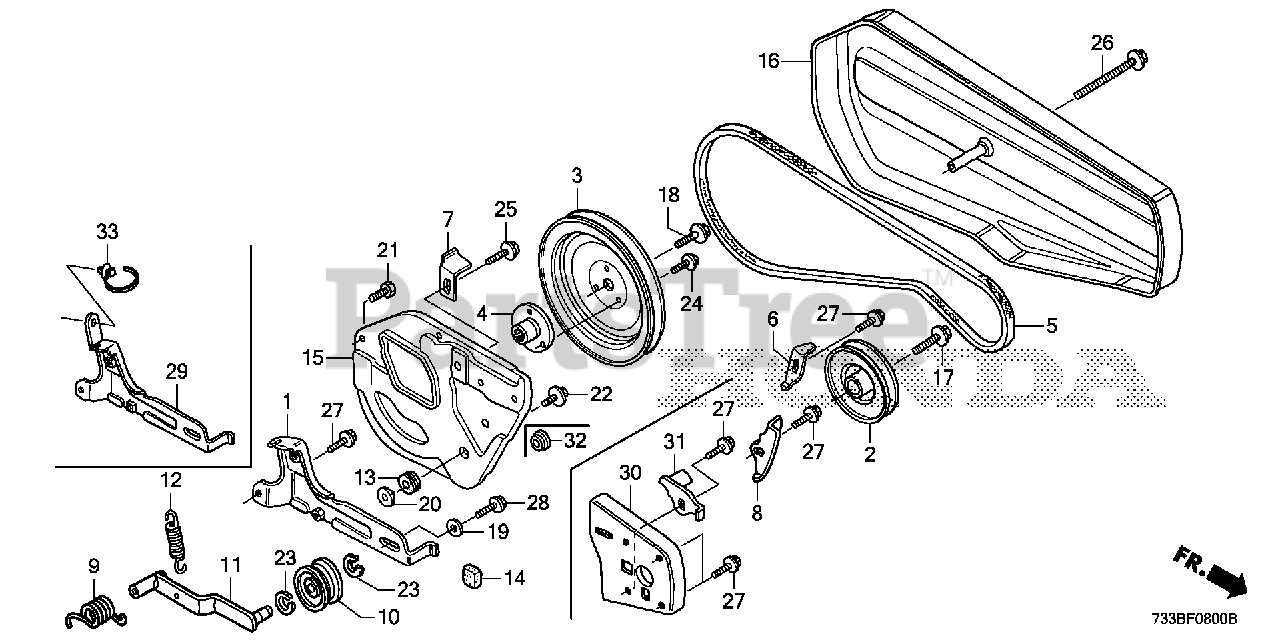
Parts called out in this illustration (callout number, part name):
2	PULLEY, DRIVE
3	PULLEY, DRIVEN
4	BOSS, DRIVEN PULLEY
5	V-BELT (SB-38)
6	STOPPER, BELT (UPPER)
7	STOPPER C, BELT
9	SPRING, TENSION ARM RETURN
10	ROLLER, TENSION
11	ARM, TENSION
12	SPRING, BELT TENSION
14	HOLDER, FUSE STAY
15	STAY, BELT COVER
16	COVER, BELT *R280* (POWER RED)
17	BOLT, FLANGE (8X22)
18	BOLT, FLANGE (8X18)
19	WASHER (8MM)
20	WASHER, NUMBER BRACKET MOUNTING
21	BOLT, HEX. (6X8)
22	BOLT-WASHER (6X16)
23	CIRCLIP, OUTER (10MM)
24	BOLT, FLANGE (6X10)
25	BOLT, FLANGE (6X12)
26	BOLT, FLANGE (6X50)
27	BOLT, FLANGE (8X16)
28	BOLT, FLANGE (8X20)
29	STAY, ENGINE
30	PLATE, ENGINE ADJUSTING
31	STOPPER, BELT (LOWER)
32	GROMMET, WIRE
33	CLIP, HARNESS BAND (145MM) (BLACK)
